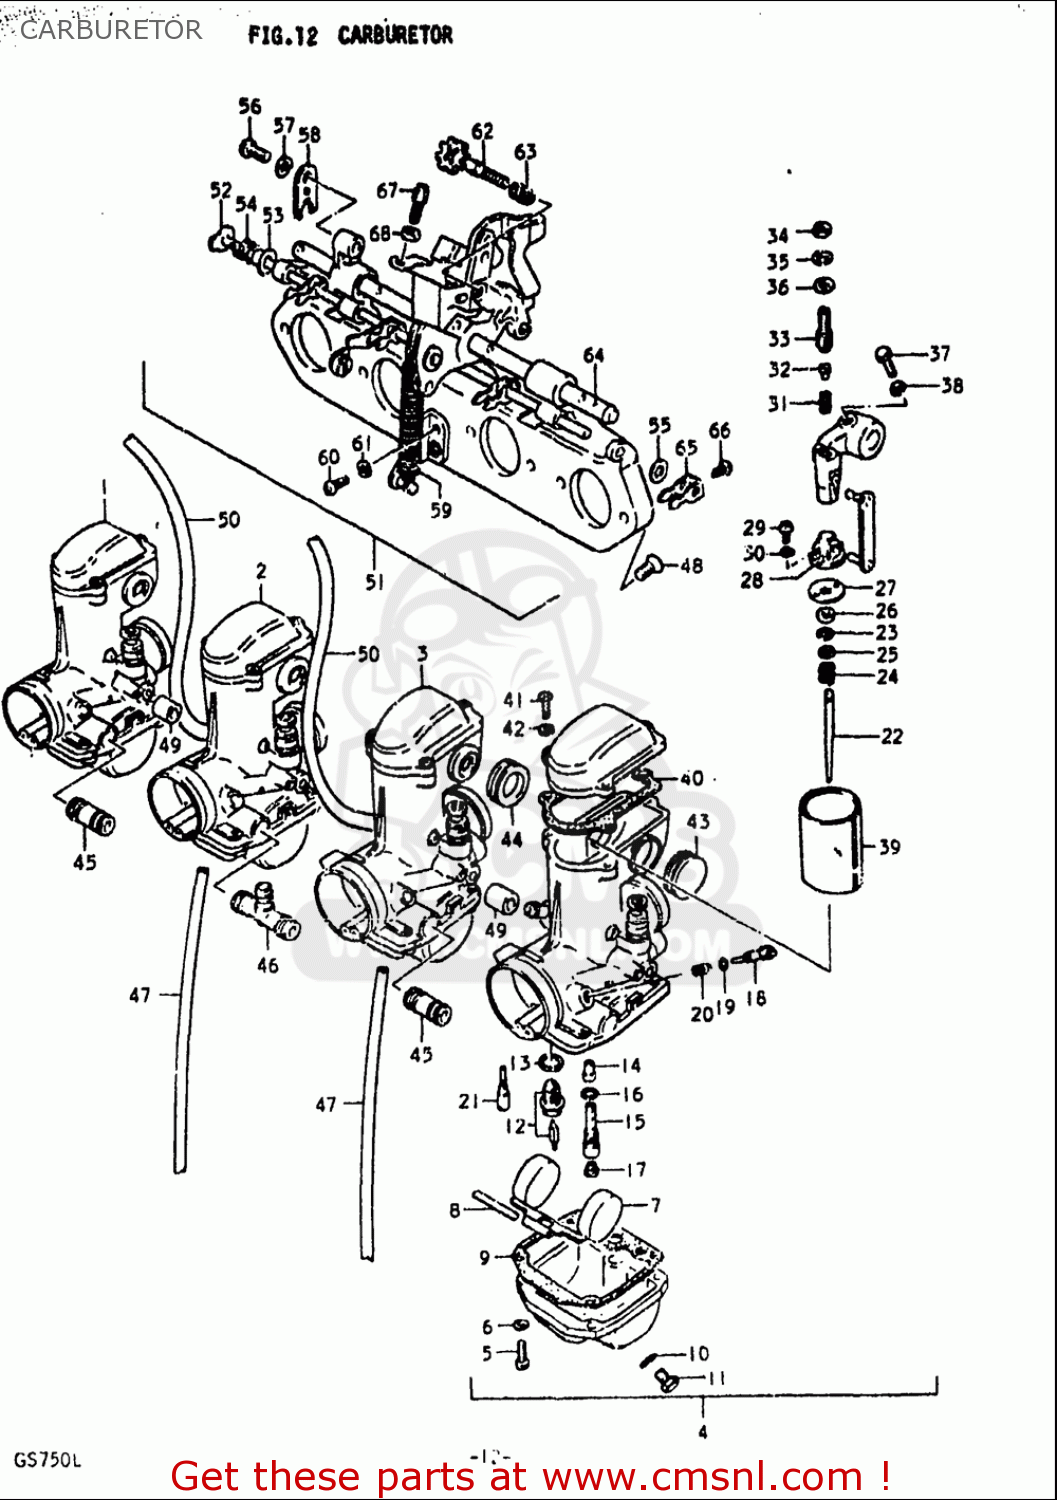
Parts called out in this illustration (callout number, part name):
5	SCREW 4X16
6	WASHER,LOCK
7	FLOAT
8	PIN,FLOAT
9	GASKET,FLOAT CHAMBER (NAS)
10	O RING
11	SCREW
12	VALVE ASSY,NEEDLE
13	GASKET,VALVE SEAT (NAS)
15	PIPE,BLEEDER
16	O RING
17	JET,MAIN(102.5)
18	SCREW,PILOT AIR
19	O RING
20	SPRING
21	JET,PILOT
22	NEEDLE,JET
23	CLIP
24	SPRING
25	WASHER,JET NEEDLE
26	RING
29	SCREW
30	WASHER,LOCK
34	NUT
35	WASHER,LOCK
36	WASHER
37	BOLT
38	WASHER,LOCK
40	GASKET (NAS)
41	SCREW
42	WASHER,LOCK
44	SEAL
48	SCREW(6X14)
49	HOSE(6X10X600)
50	HOSE(4.5X8.5X600)
53	WASHER
55	WASHER,STARTER SHAFT
56	SCREW
57	WASHER,LOCK
59	SPRING,THROTTLE RETURN
60	SCREW
61	WASHER,LOCK
66	SCREW
67	ADJUSTER,CABLE
68	NUT
